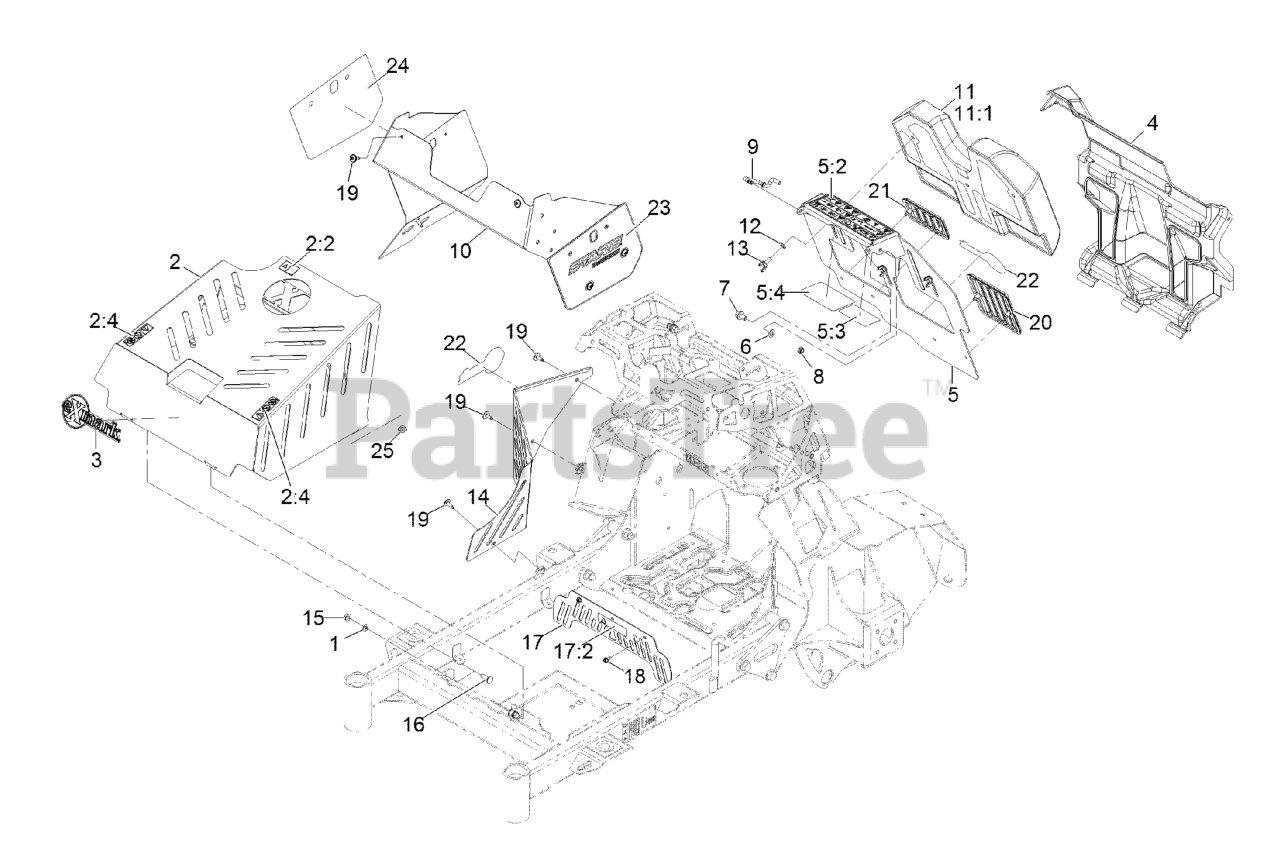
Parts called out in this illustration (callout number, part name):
1	SPACER-NYLON
2	ASM-COVER W DECALS
2:2	DECAL-WARNING
2:4	DECAL-NO STEP/RIDERS
3	DECAL, EXMARK LOGO
4	COVER-REAR
5	ASM, PAD BACKING W/ DECALS
5:2	DECAL-WARNING
5:3	DECAL-DRIVE RELEASE
5:4	DECAL-SERVICE AID SM
6	WASHER-THRUST
7	SCREW-HHF
9	ROD, PROP
10	COVER-TOWER
11	PAD-THIGH
11:1	COVER, PAD
12	WASHER-BELLEVILLE
13	SCREW, THUMB
14	COVER-RH SIDE
16	BOLT-CARR
17	ASM, BELT GUARD W/ DECAL
17:2	DECAL-WARNING
18	SCREW-HWH
19	SCREW, TORX
20	PAD, KNEE, LT
21	PAD, KNEE, RT
22	DECAL-EXMARK LOGO
23	DECAL-STARIS LOGO LT
24	DECAL-STARIS LOGO RT
